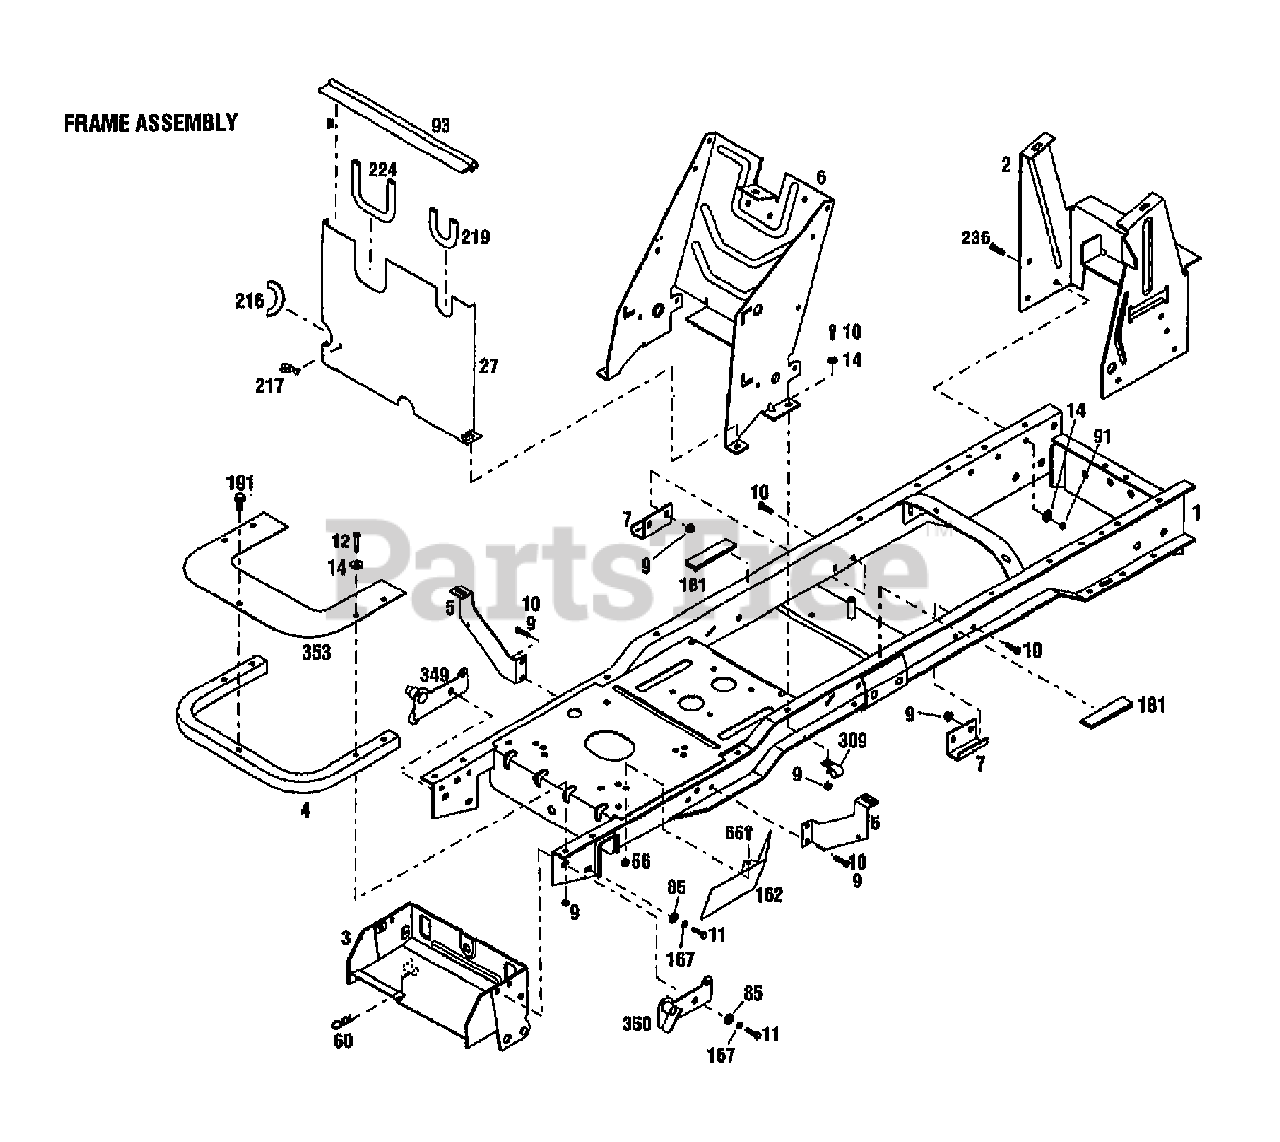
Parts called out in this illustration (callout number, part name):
1	ASSM-FRAME LTX {13096/097}
1	ASSM-FRAME {13099}
2	SUPPORT-REAR TANK
3	ASSM-BRKT ATTACHMENT
4	BUMPER-FRONT
5	SUPPORT-FENDER
6	SUPPORT-CONSOLE
7	STOP-MOWER DECK
9	NUT-HFLK 5/16-18 ZP
10	SCR-HHC 5/16-18X.75 GR 5 ZP
11	SCR-HH 3/8-16X1.0 G5 ZP
12	SCR-HH 5/16-18X1.75
14	WASHER-FLAT 5/16 SAE
27	SHIELD-HEAT {13099}
56	NUT-HF/LK 1/4-20 ZP
60	PIN-HITCH .125X2.56 ZP
65	SCR-HH 1/4-20X.625
85	WASHER-FLAT 3/8 SAE
91	NUT-TOP/LK 5/16-18 ZP
93	GASKET-HEAT SHIELD {13099}
162	SHIELD-HEAT UPPER {13099}
167	WASHER-LK .375 @ DEPL
191	SCR-FLANGE 1/4-20X3/4 GR5
216	TRIM {13099}
217	HANGER-CABLE {13099}
219	TRIM {13099}
224	TRIM-HEAT SHIELD {13099}
236	SCR-HFLK 5/16-18X.75 ZP
309	CLIP-J
349	PLATE-PIVOT RH
350	PLATE-PIVOT LH
353	SHIELD-HEAT {13099}
